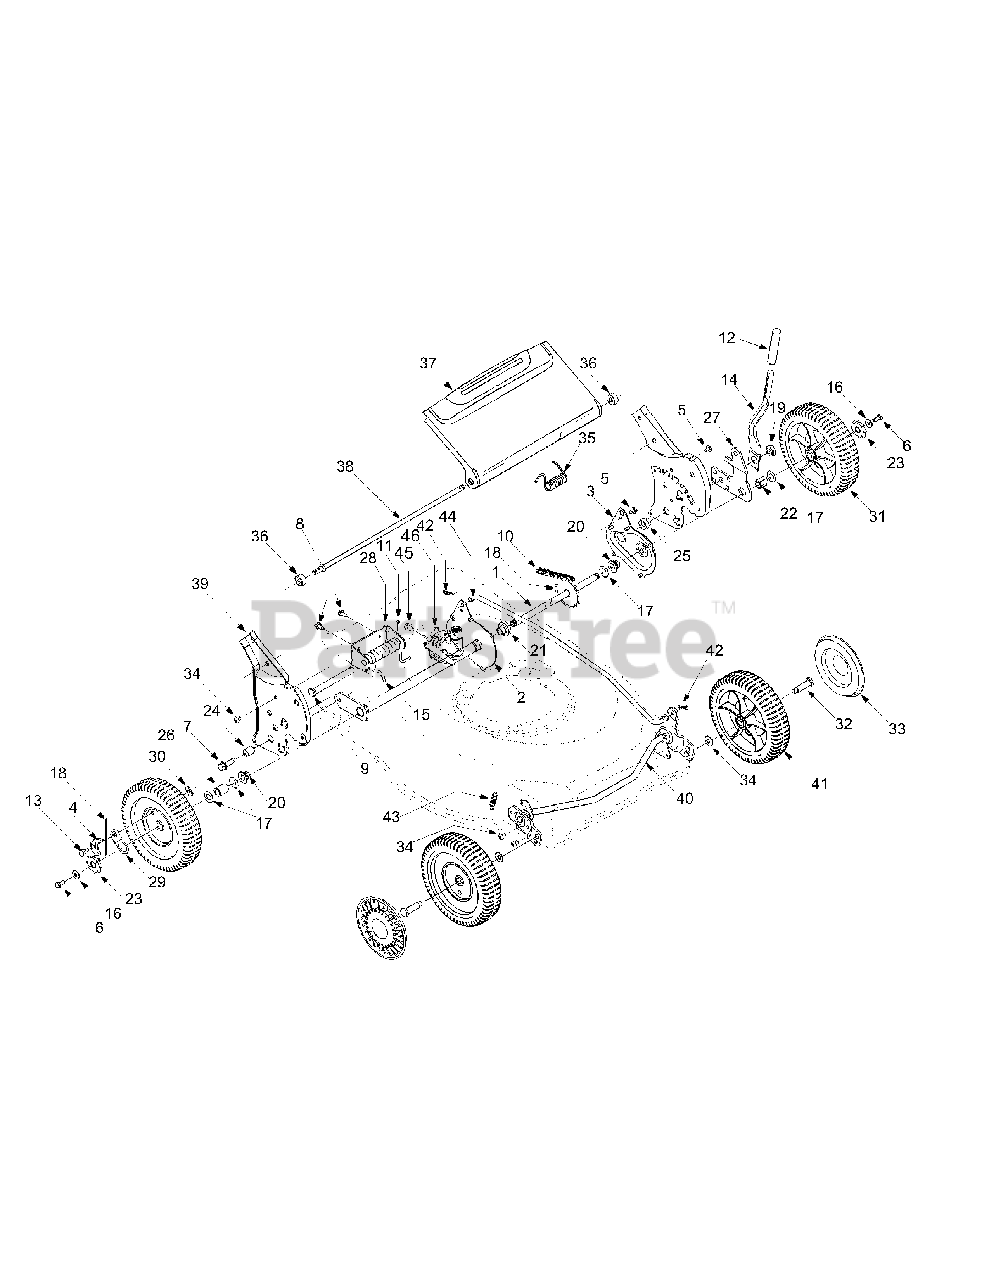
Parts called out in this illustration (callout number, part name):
1	Rear Axle Assembly
2	Trans axle Assembly
4	Pawl LH
5	TT Screw 1/4-20 x 0.375"
6	Hex Bolt 1/4-20 x 0.620"
7	TT Screw 3/8-16 x 1.25"
8	TT Screw 1/4-20 x 0.625"
9	Clevis Pin
10	Chain
11	Cotter Pin
12	Foam Grip
13	Shoulder Screw
14	Height Adjustment Lever
15	Torsion Spring RH
16	Bell Washer
17	Flat Washer
18	Ratchet Spring
19	Shoulder Nut
20	Hex Flange Bearing
21	Hex Flange Bearing
22	Hex Slev Bearing
23	Ratchet Wheel
24	Spacer
25	Shoulder Spacer
26	Slev Spacer
27	Pivot Arm
28	Lift Assist Bracket
29	Pawl Plate: Ratchet
30	Top Lock Weld Nut
31	Wheel
32	Shoulder Screw
33	Hubcap
34	AB Screw 1/4-14 x 0.5"
35	Torsion Spring LH
36	Shoulder Spacer
37	Grass Bag Door
38	Pivot Rod
41	Bell Washer
42	Cotter Pin
43	Extension Spring
44	Adjustment Rod
46	Transmission
